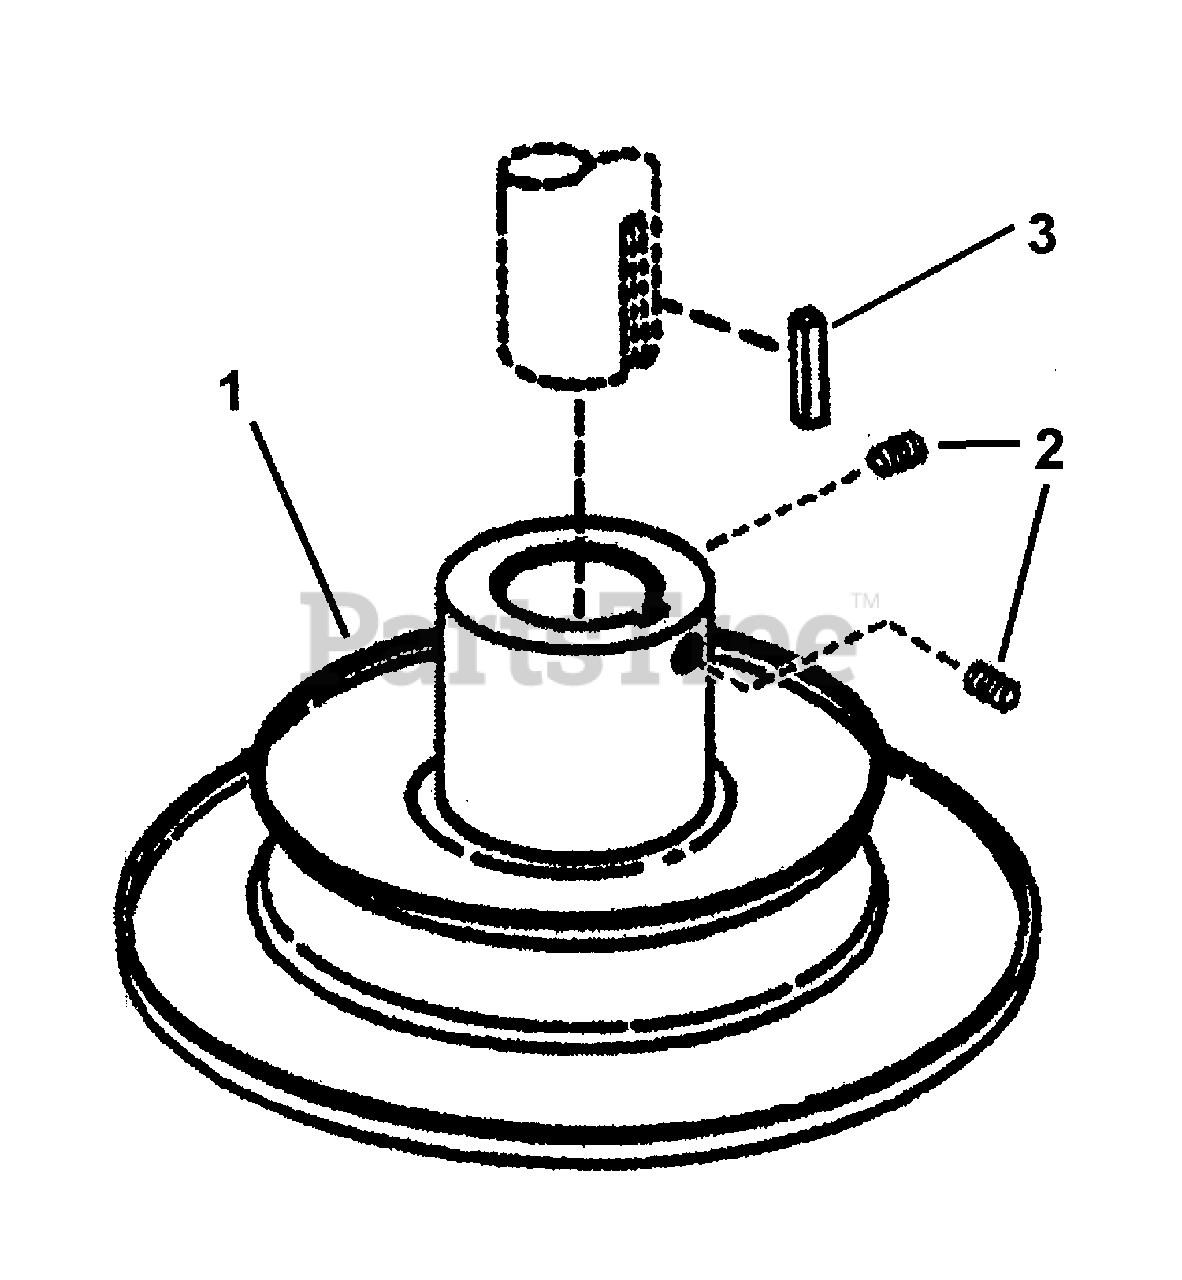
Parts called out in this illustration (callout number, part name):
1	WELDMENT, 5.75" O.D. Drive Disc
2	SET SCREW, HRSS, 3/8-16 x 3/8"
3	KEY,1/4" Square x 2" Long
